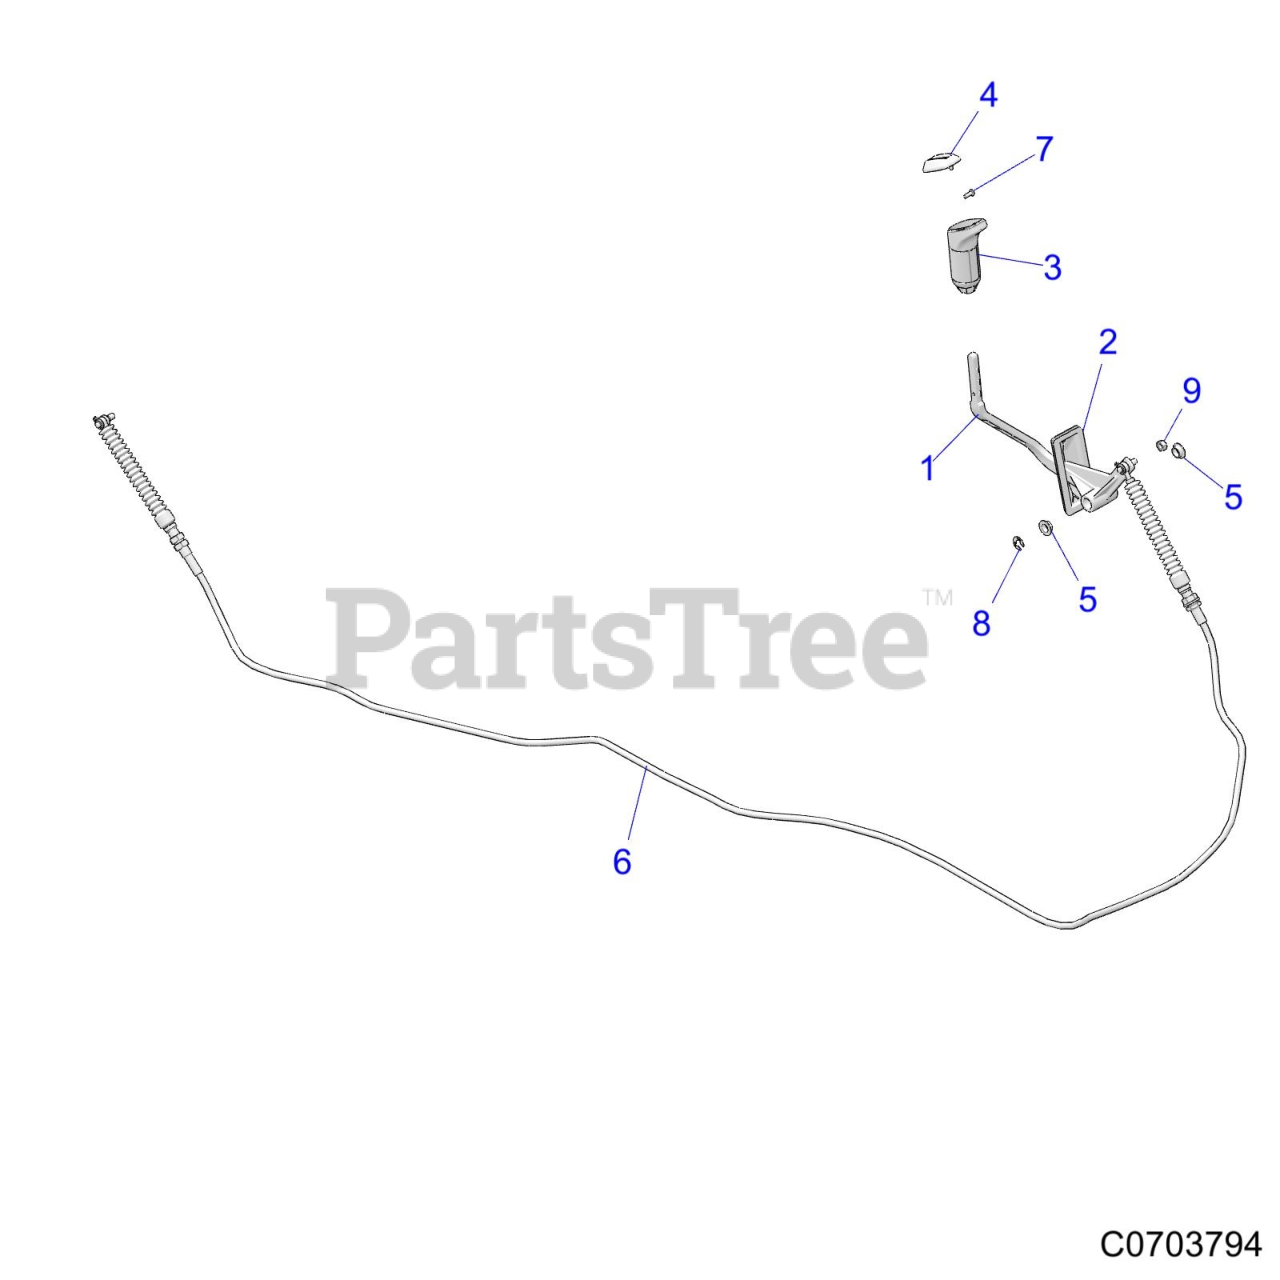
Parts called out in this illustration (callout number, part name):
1	SHIFT-LEVER,CAST,M.BLK
2	GROMMET-SHIFTER
3	KNOB-SHIFTER,BLK
4	COVER-SHIFTER KNOB,BLK
5	BUSHING-PEDAL PIVOT
6	CABLE-SHIFTER,GAS
9	NUT,NYLOK M8X1.25(10) *
